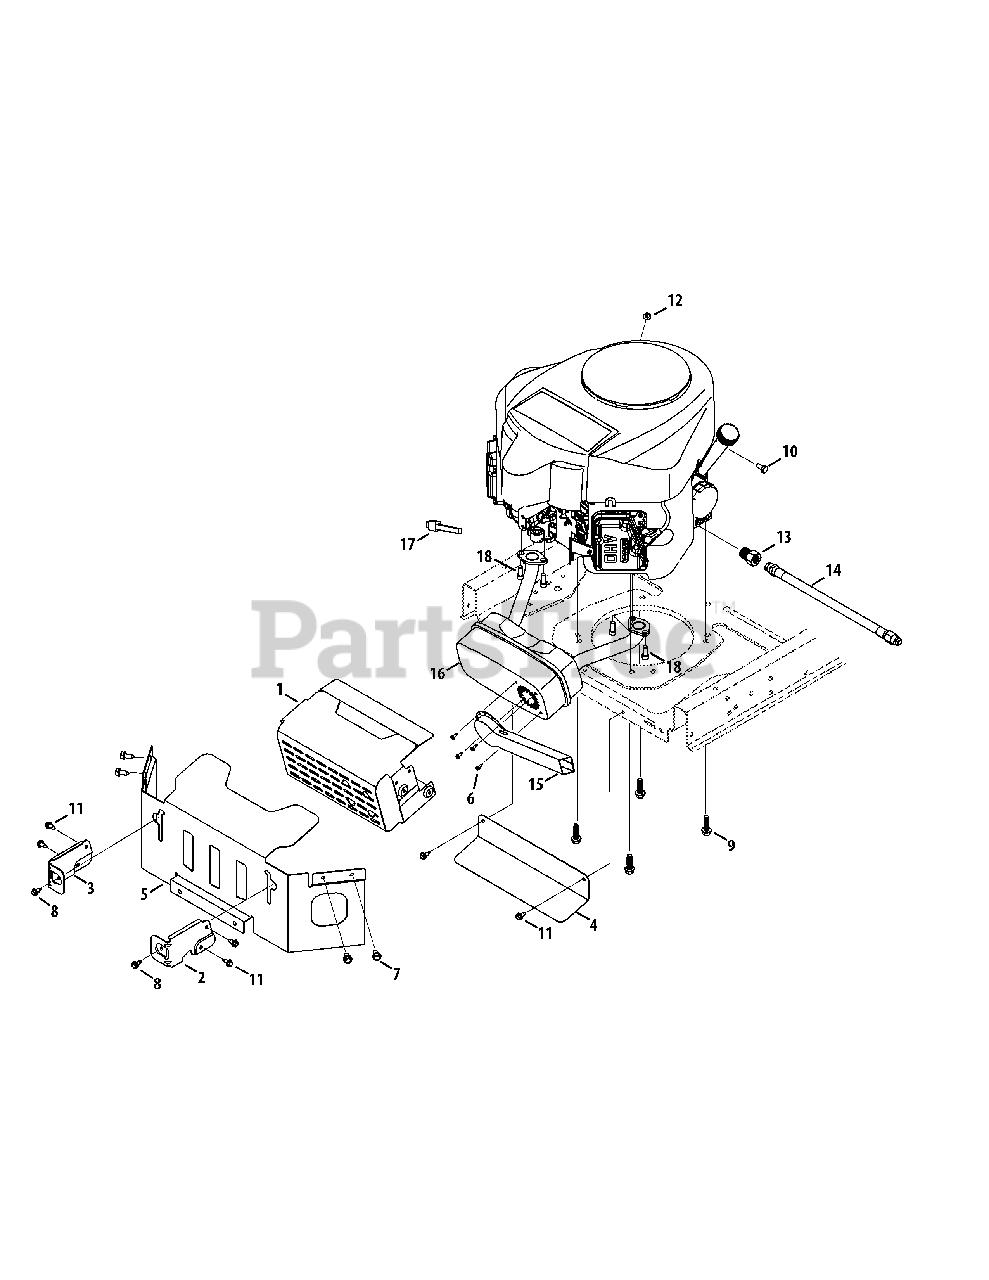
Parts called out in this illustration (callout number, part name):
1	Muffler Shield Assembly
2	Muffler Shield Bracket, RH
3	Muffler Shield Bracket, LH
4	Lower Heat Shield
5	Muffler Shield
6	Hex Washer Screw, #8-18 x .500
7	Hex Washer Screw, 5/16-18 x .750
8	Screw, 1/4-20 x .375
9	Screw, 3/8-16 x 1.25, Kaw.
10	Hex Cap Screw, M8-1.25 x 16, Kaw.
11	Hex Washer Screw, 1/4-20 x .625
12	Flange Lock Nut, 1/4-20
13	Fitting, 1.0 Hex x M20, Kaw.
14	Oil Drain Hose
15	Muffler Deflector Long
16	Twin Muffler, Kaw.
17	Cable Tie, Kaw.
18	Socket Hd Screw, 5/16-18 x .750, Koh.
